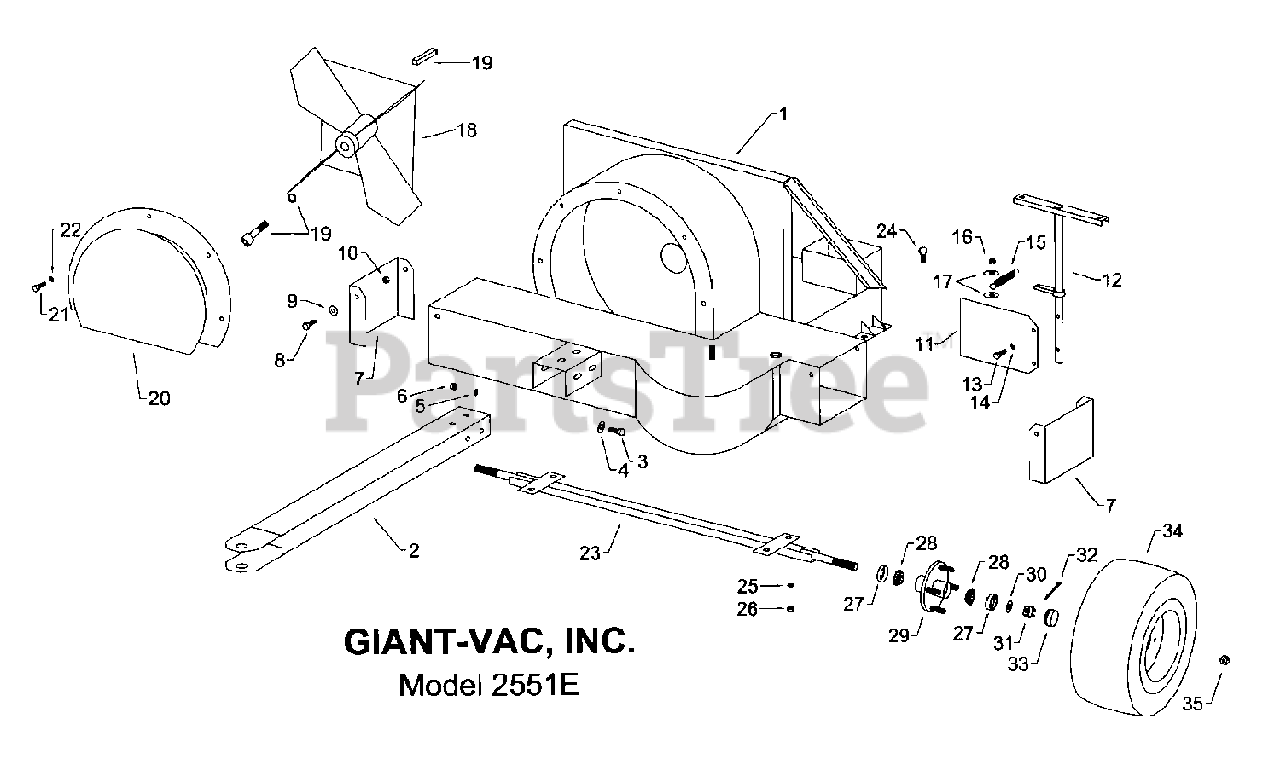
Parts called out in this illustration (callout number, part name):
1	Housing & base assy
3	3/8-16 x 1 hex bolt (draw bar to housing assy)
4	3/8 flat washer
5	3/8 lock washer
6	3/8-16 hex nut
7	Side discharge deflector
8	3/8-16 x 1 hex bolt (side deflector to housing assy)
9	3/8 flat washer
10	3/8-16 lock nut
11	Inner discharge direction door
12	Direction door control rod assy
13	5/16-18 x 3/4 hex bolt (direction door to control rod)
14	5/16 lock washer
15	Discharge door return spring
16	3/8-16 lock nut (spring to housing assy)
17	3/8 flat washer
19	Impeller bolt & key group
20	Intake baffle
21	5/16-18 x 3/4 hex bolt (intake baffle to housing assy)
22	5/16 lock washer
24	1/2-13 x 1-1/4 hex bolt (axle to housing assy)
25	1/2 lock washer
26	1/2-13 hex nut
27	Bearing seal
28	High speed bearing – 1 set of 2
29	Hub - less bearing – 4-lug w/studs
30	3/4 flat washer
31	Castle nut – 3/4-25 – secures hub to axle
32	Cotter pin – 1/8 x 1-1/2 oal
34	Tire & rim assy – 16-6.50 x 8 – 4-lug
